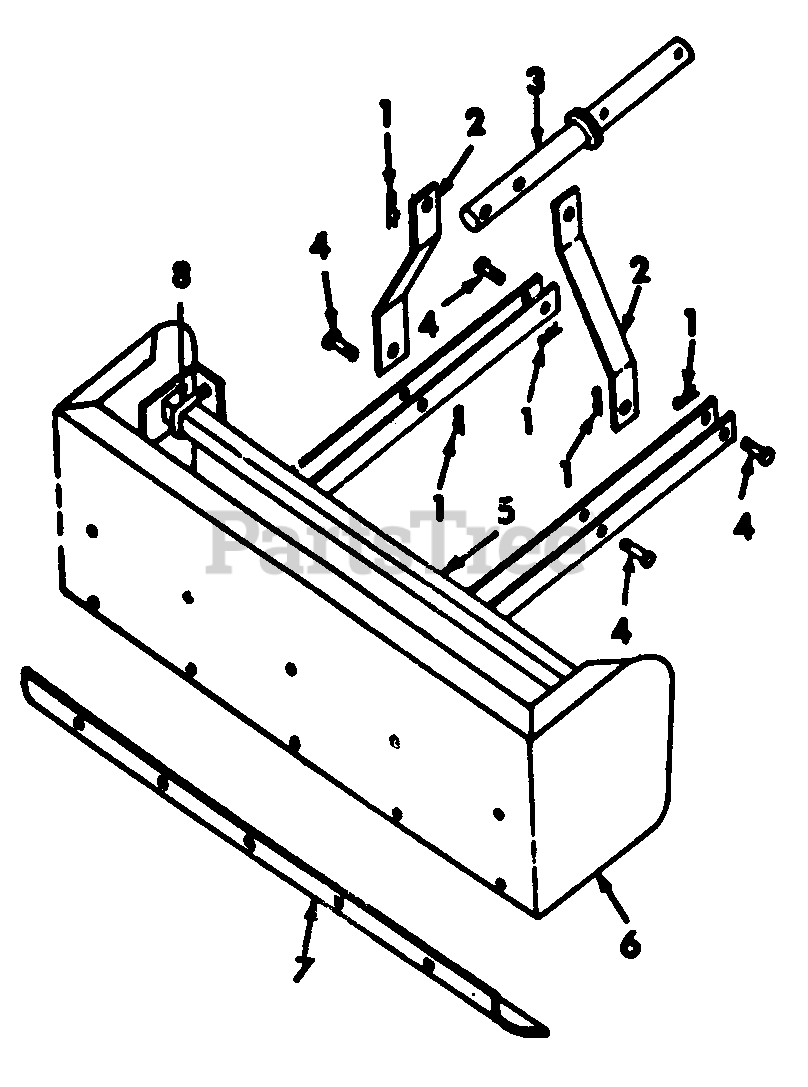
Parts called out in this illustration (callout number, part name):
1	Pin, Quick Attachable Cotter
2	Bar, Lift Link
3	Pin Assy, Hitch Lift
4	Pin, 1/2 X 1-1/8 Std-Hd
5	Lift Link Assy
6	Bucket Assy
